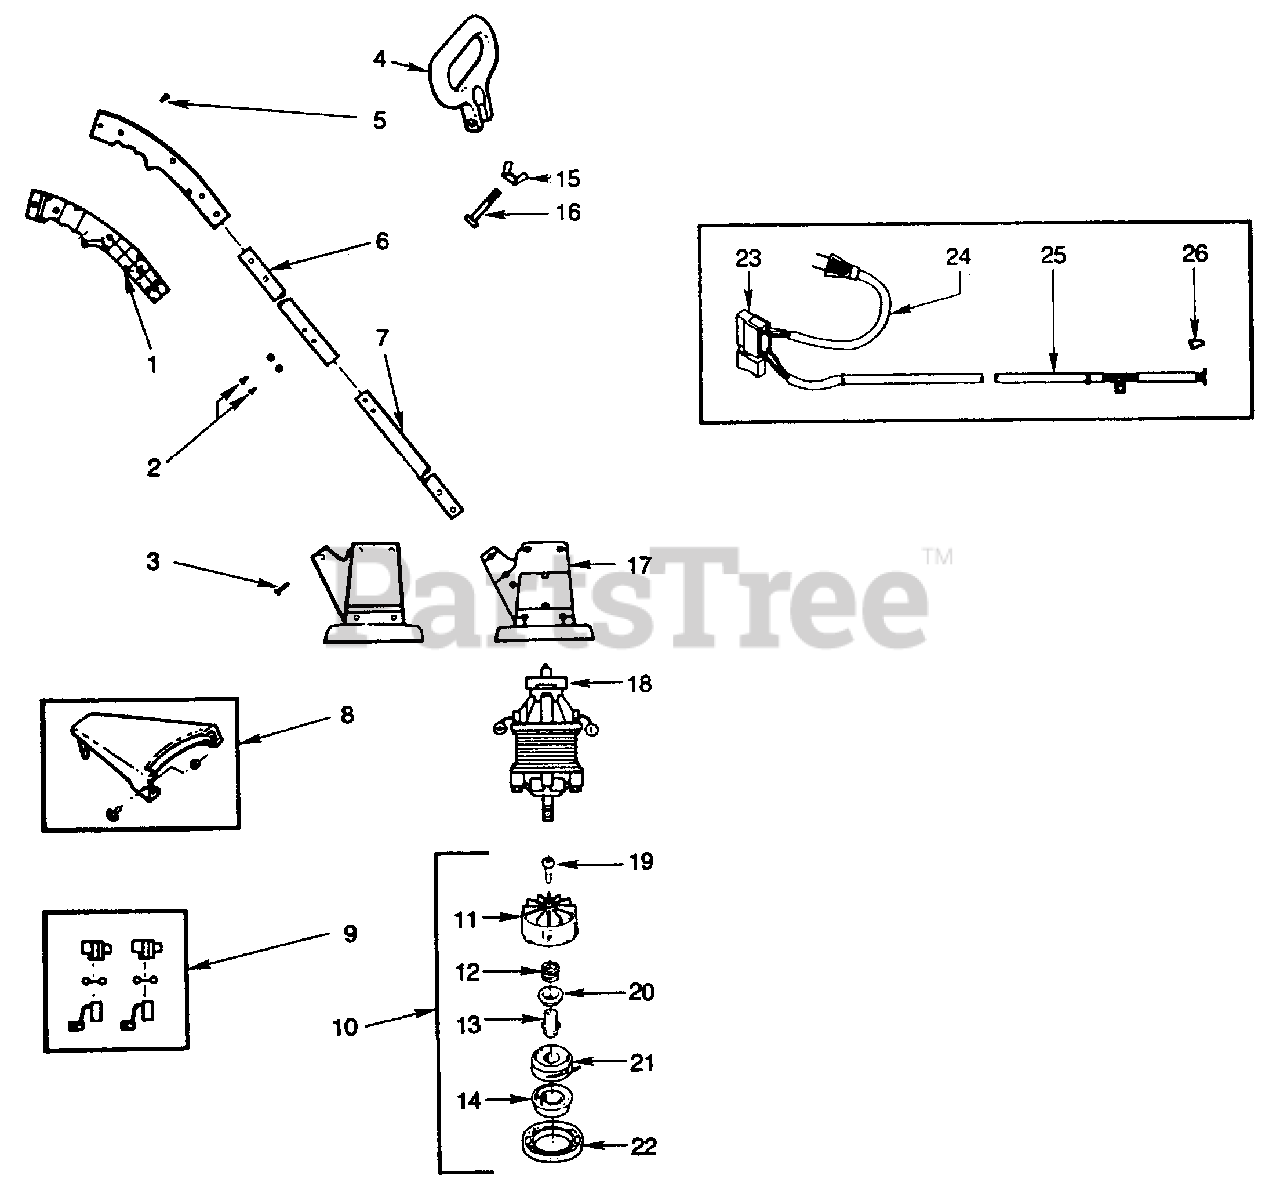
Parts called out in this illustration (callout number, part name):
1	TRIGGER HANDLE SET
2	TUBE FASTNER KIT
3	SCREW
4	ASSIST HANDLE
5	SCREW
6	TUBE,UPPER
7	TUBE, LOWER
8	LINE LIMITER ASSEMBLY
9	BRUSH KIT
10	TAP-N-GO HEAD ASSEMBLY
11	HUB W/LINE SAVER
12	SPRING
13	DRIVE GEAR
14	RELEASE BUTTON
15	WING NUT
17	MOTOR HOUSING SET
19	DRIVE ADAPTOR
20	SPRING ADAPTOR
21	SPOOL WOUND
22	COVER
23	SWITCH
24	POWER CORD PIGTAIL
25	HARNESS W/DIODE
26	CONNECTOR
